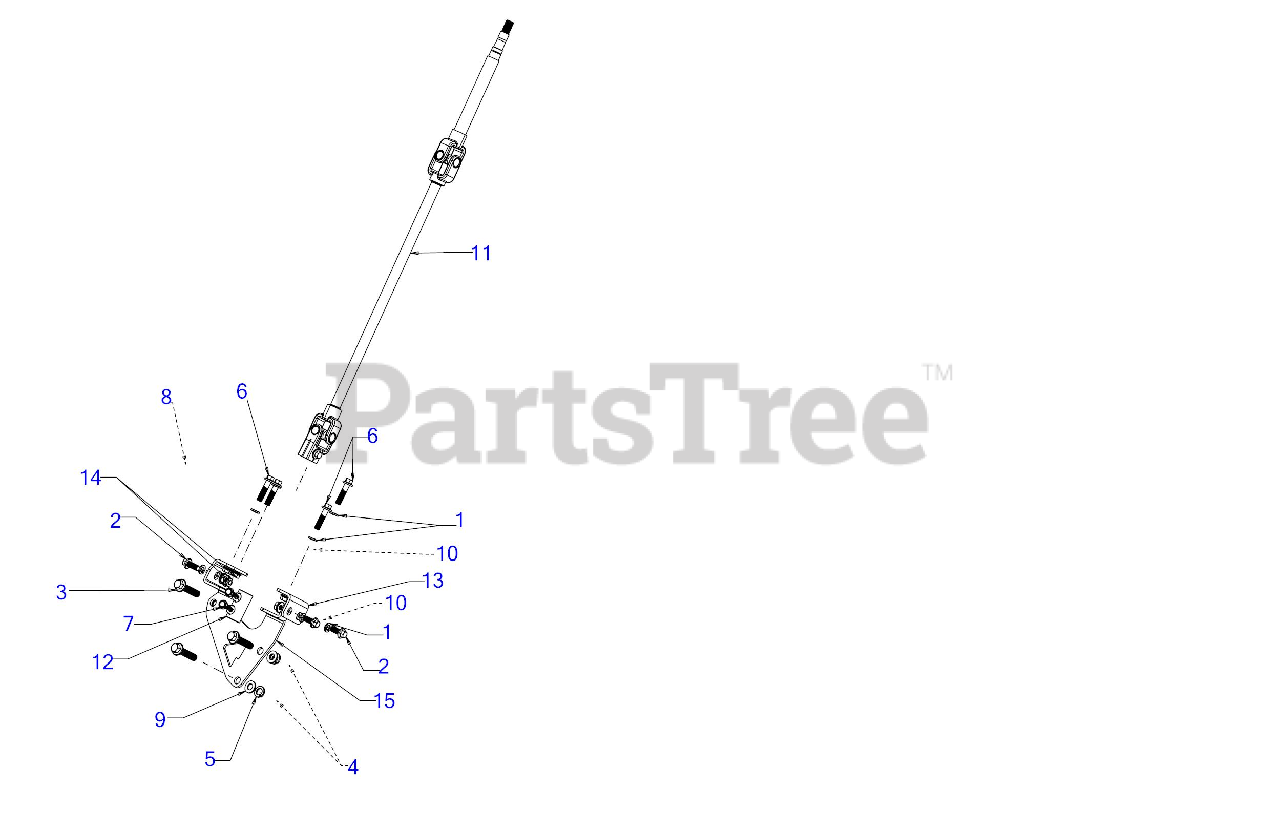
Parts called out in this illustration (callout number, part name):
1	SPRING WASHER-8
2	HEXAGON FLANGE BOLT M8X20
3	HEX FLANGE BOLT M10X1.25X45
4	HEX FLANGE SELF LOCK NUT
5	SPRING WASHER
6	HEXAGON FLANGE BOLTS M8X35
7	HEXAGON FLANGE BOLT M6X40
8	ELECTRICAL POWER STEERING COMP
11	STEERING WHEEL SHAFT
12	SHAFT COUPLING
13	EPS BRACKET
14	NUT M8-1.25
15	EPS MOUNT BRACKET
